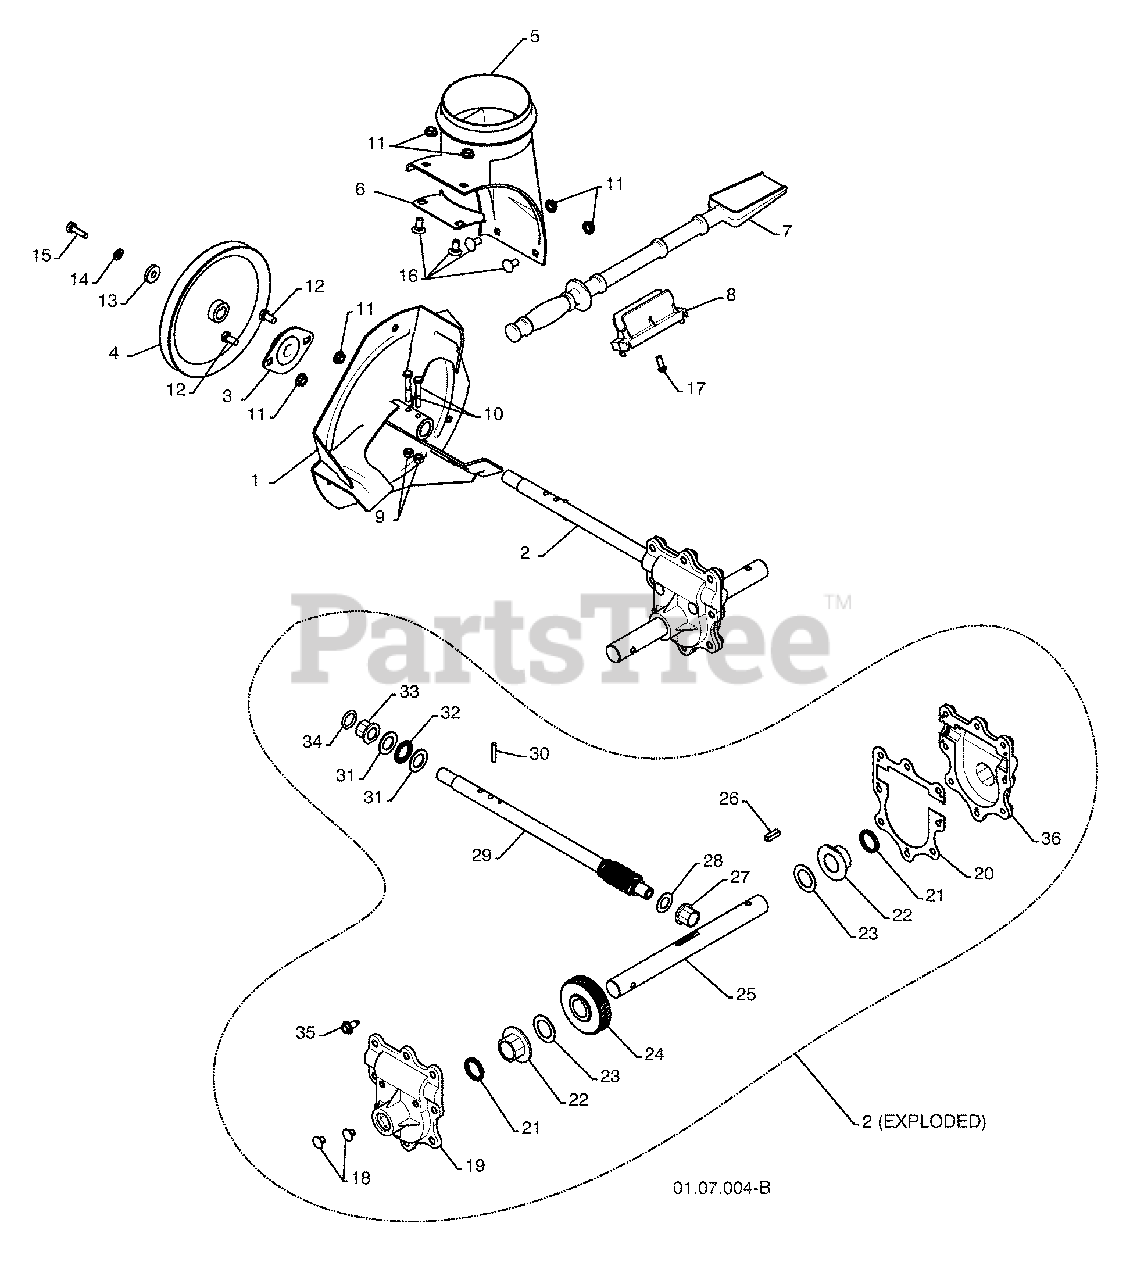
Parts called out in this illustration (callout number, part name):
1	IMPELLER
2	GEARBOX ASSEMBLY
4	IMPELLER PULLEY
5	DISCHARGE BASE
6	CORNER BRACKET
7	CLEAN OUT TOOL
9	NUT 1/4--20
10	SCREW 1/4--20 X .625
11	NUT 5/16--18
12	SCREW 5/16--18 X .625
14	LOCKWASHER 5/16
15	SCREW 5/16--18 X 1.00
16	CARRIAGE BOLT
17	SCREW 13--16 X .625
18	PLUG
19	GEARBOX COVER RH
20	GASKET
21	SEAL
22	BEARING
23	THRUST WASHER 1.00
24	WORM GEAR
25	AUGER SHAFT
26	SQUARE KEY
27	BEARING
28	THRUST WASHER
29	IMPELLER SHAFT
30	ROLL PIN
31	THRUST WASHER
32	THRUST BEARING
35	SCREW 5/16--18 X .750
36	GEARBOX COVER LH
